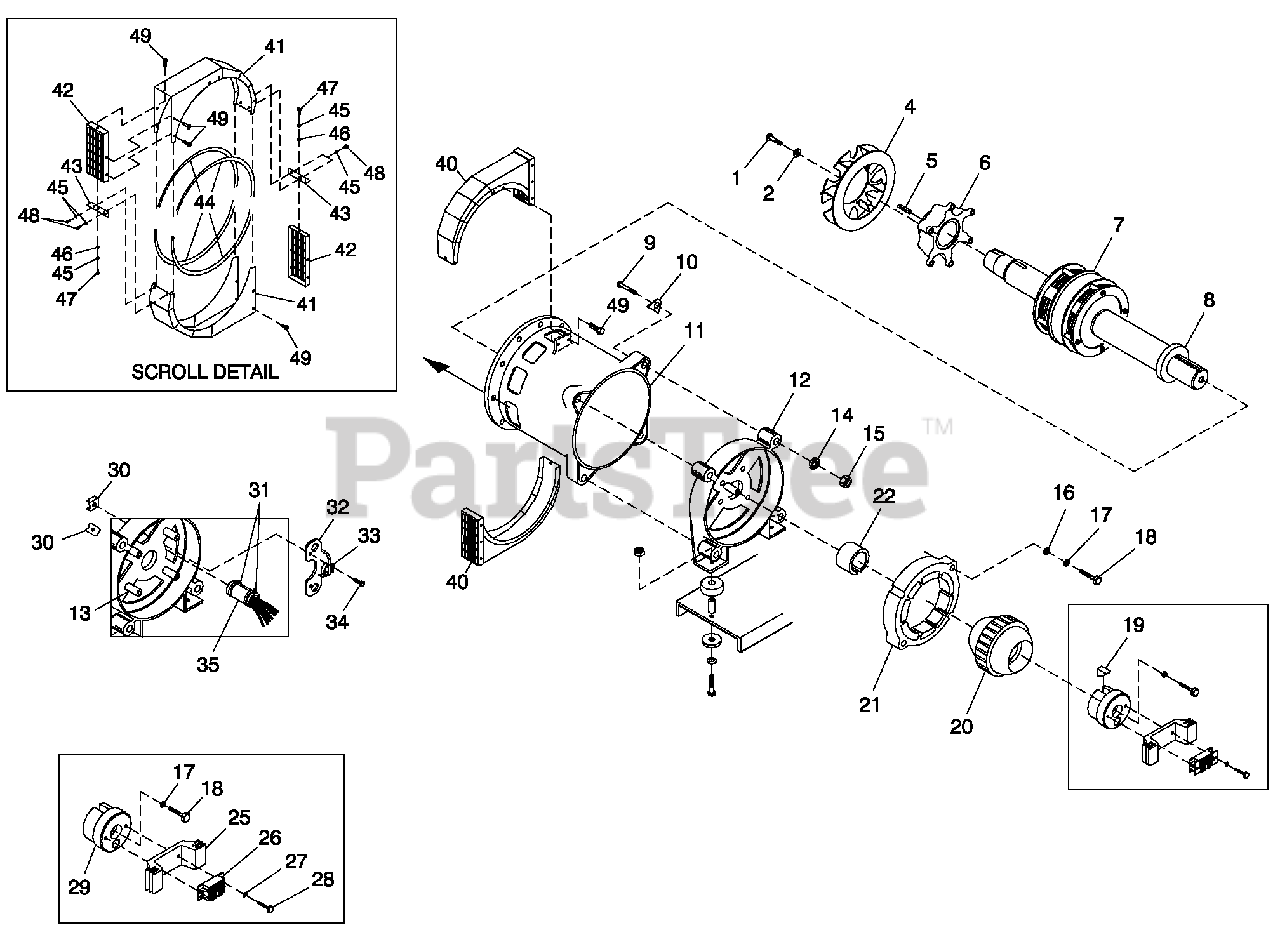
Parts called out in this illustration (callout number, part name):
1	SCREW HHC M8-1.25 X 20 G10.9
2	WASHER LOCK M8-5/16
4	FAN SAE ALTERNATOR (G/B)
5	KEY SQ 3/8X1-9/16 STEEL
6	HU B DRIVE 390 SAE G B
7	RTR 390 100K B3 G B SAE TECHUM
8	BEARING BALL 6212 SEALED
9	SCREW HHC M14-2.0 X 140 G8.8
10	WASHER 390 SAE ALT.
11	STR-390-80LB3 SAE
12	CARRIER REAR BRG 15"
13	PIN DOWEL 1/2 X 1-1/4
14	WASHER LOCK M14
15	NUTHEXM14-2.0 G8 YEL CHR
16	WASHER FLAT M12
17	WASHER LOCK M12
18	SCREW HHC M12-1.75 X 60 G10.9
19	KEY SQ 3/8 X 3-1/4 STEEL
20	ASSY EXCITER 2.00" STK
21	EXITER FIELD 2" LG SPD CONN
22	COLLAR SLIP FIT 390 MM
25	BRIDGE SUPPORT DIODE 15"
26	ASSY BRIDGE RECTIFIER
27	WASHER SHAKEPROOFINT #8
28	SCREW HHM #8-32X7/8
29	CAP END ROTOR 390MM
30	PLATE NUT
31	TIE WRAP UL 14.6 X .14 NATL
32	BRACKET-STATORWIRE
33	CLAMP HOSE #36 1.88-2.7
34	SCREW HHC 5/16-18 X 1-1/4 G5
35	SLEEVE RU BBER
40	ASSY SCROLL 390 SAE
41	SHROUD ALT SHEET METAL
42	SCREEN SHROUD SAE
43	BRKT TENSIONER SAE SCROLL
44	TRIM VINYL BLACK 1/8 GP
45	WASHER LOCK M6-1/4
46	WASHER FLAT 1/4-M6 ZINC
47	SCREW HHC M6-1.0X 25 G8.8
48	SCREW HHC M6-1.0X 16 G8.8
49	SCREW SWAGE 1/4-20 X 1/2 ZYC
